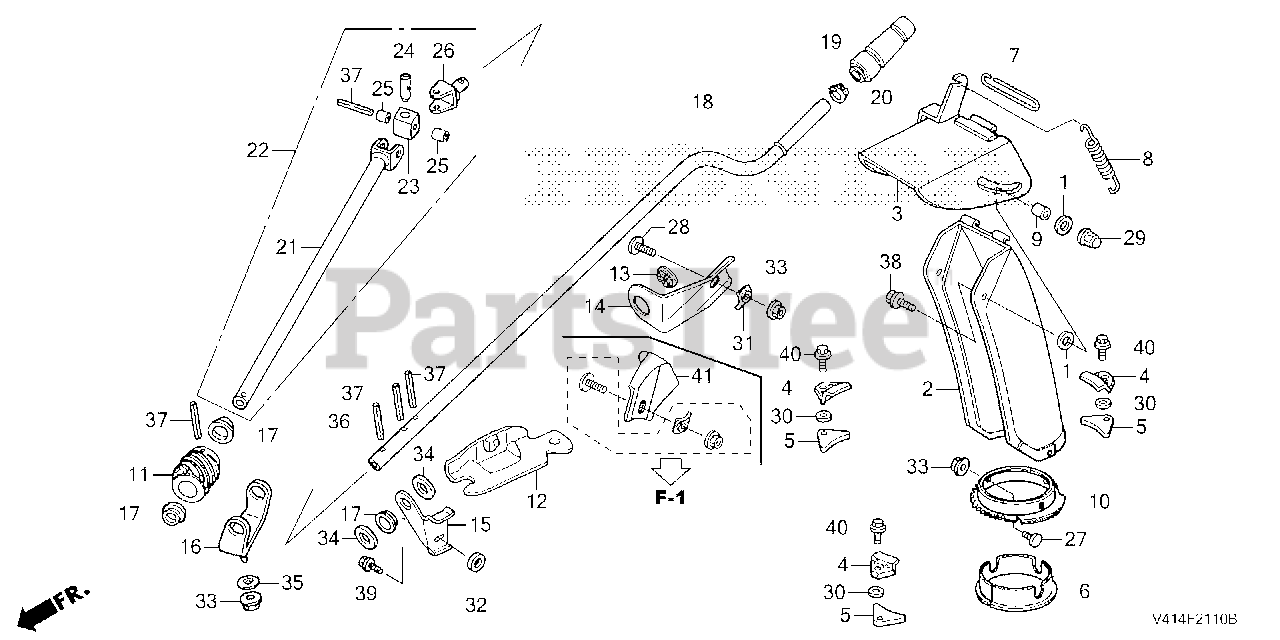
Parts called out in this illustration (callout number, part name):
1	WASHER, ACCELERATOR PEDAL
2	CHUTE
3	GUIDE, CHUTE (COO)
4	PLATE, CHUTE SETTING
5	PLATE, CHUTE SETTING (B)
6	BUSH, CHUTE
7	PIN, CHUTE GUIDE
8	SPRING, CHUTE
9	COLLAR, CHUTE GUIDE
10	GEAR, CHUTE
11	GEAR, CHUTE DRIVE
12	HOLDER, HANDLE BRACKET
13	BUSH, CHUTE HANDLE
14	BRACKET A, CHUTE HANDLE
15	BRACKET B, CHUTE HANDLE
16	STAY, DRIVE GEAR
17	BUSH, DRIVE GEAR
18	HANDLE, CHUTE (UPPER)
19	GRIP, CHUTE HANDLE
20	BUSH A, CHUTE HANDLE
22	HANDLE, CHUTE (LOWER)
23	PIECE, JOINT
24	PIN A, JOINT
25	PIN B, JOINT
27	BOLT, SPECIAL (9X15)
28	BOLT, HANDLE HOLDER
29	NUT, CAP (6MM)
30	WASHER, CHUTE SETTING
31	WASHER, FRAME JOINT
33	NUT, FLANGE (8MM)
34	WASHER, PLAIN (16MM)
35	WASHER, PLAIN (8MM)
36	PIN, SPRING (4X22)
37	PIN, SPRING (4X28)
38	BOLT, FLANGE (6X14)
39	BOLT, FLANGE (6X12) Use up to Engine SN 1543277.
40	BOLT, FLANGE (8X16) Use from Engine SN 1000016.
